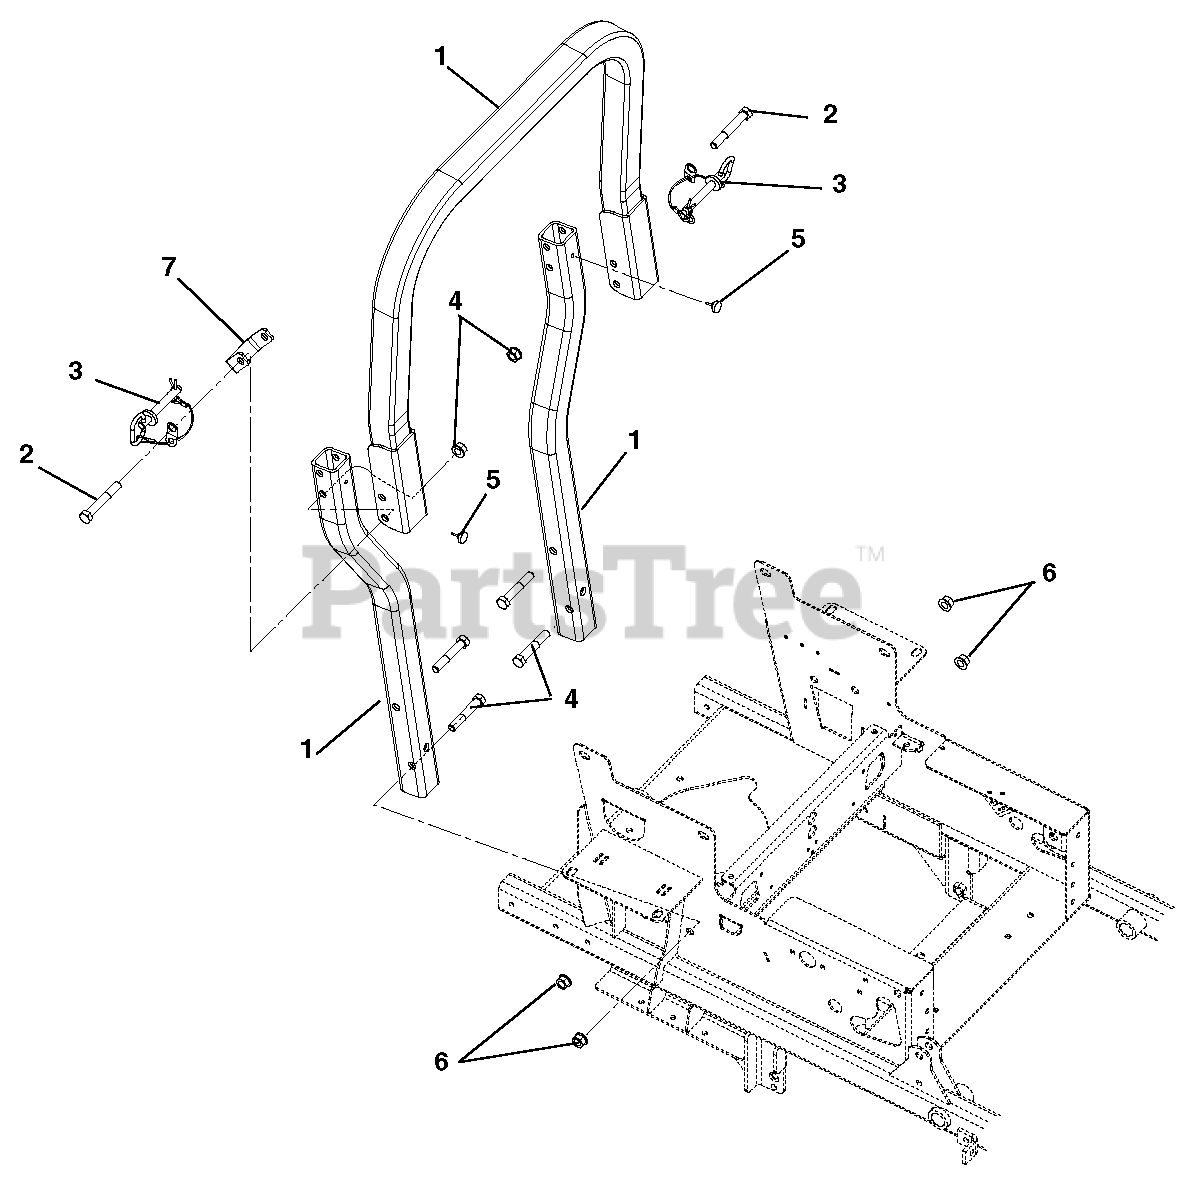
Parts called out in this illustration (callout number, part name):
1	ROPS, PT100 Replacement
2	Bolt, Hex .50-13 x 3.50 Grade 5
3	Assembly, ROPS PIN/LANYARD
4	Nut, Locking-Top-Flange .50-13
5	Bumper, ROPS Rubber
6	Bolt, Hex .50-13 x 3.00 Grade 5
7	Bracket, ROPS Stop, Pro-TURN
